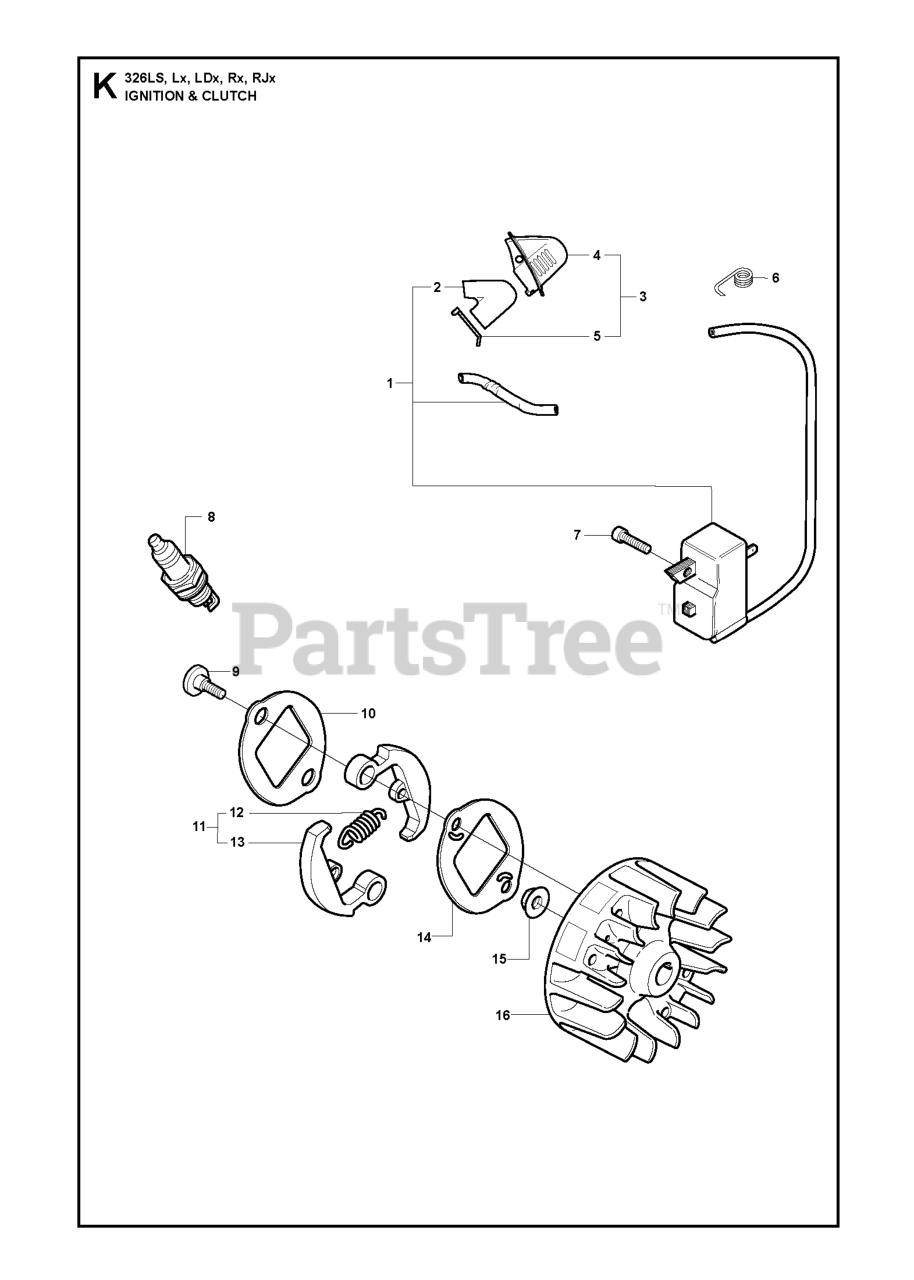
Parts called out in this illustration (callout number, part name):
1	IGNITION MODULE MB50
2	SPARK PLUG CONNECTION
6	SPRING
7	SCREW
8	SPARK PLUG RCJ6Y NLA
10	WASHER, CLUTCH
15	FLANGE NUT
